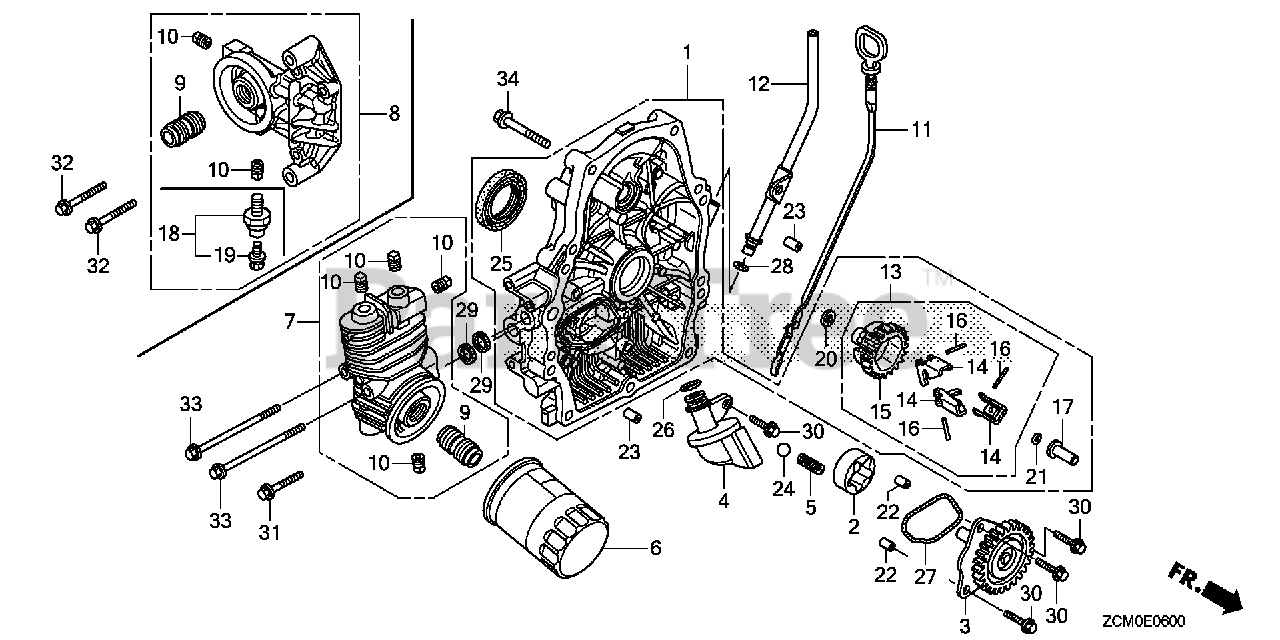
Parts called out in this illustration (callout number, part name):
1	COVER ASSY., CRANKCASE (NOT AVAILABLE)
2	ROTOR, OIL PUMP (OUTER)
3	GEAR, OIL PUMP
4	STRAINER, OIL
5	SPRING, RELIEF VALVE
6	FILTER, OIL
7	BASE, OIL FILTER
9	HOLDER, OIL FILTER
10	BOLT, SEALING
11	GAUGE, OIL LEVEL
12	PIPE, OIL LEVEL
13	GOVERNOR ASSY.
14	WEIGHT, GOVERNOR
15	HOLDER, GOVERNOR WEIGHT
16	PIN, GOVERNOR WEIGHT
17	SLIDER, GOVERNOR
20	WASHER (6X16)
21	CLIP, GOVERNOR HOLDER
22	PIN, DOWEL (8X10)
23	PIN, DOWEL (8X14)
24	BALL, STEEL (#15) (15/32)
25	OIL SEAL (38X58X9)
26	O-RING (14.8X2.4)
27	O-RING, OIL PUMP
28	O-RING (8.8X1.9)
29	GASKET, OIL PASSAGE
30	BOLT, FLANGE (6X20)
31	BOLT, FLANGE (6X28)
33	BOLT, FLANGE (6X90)
34	BOLT, FLANGE (8X45)
